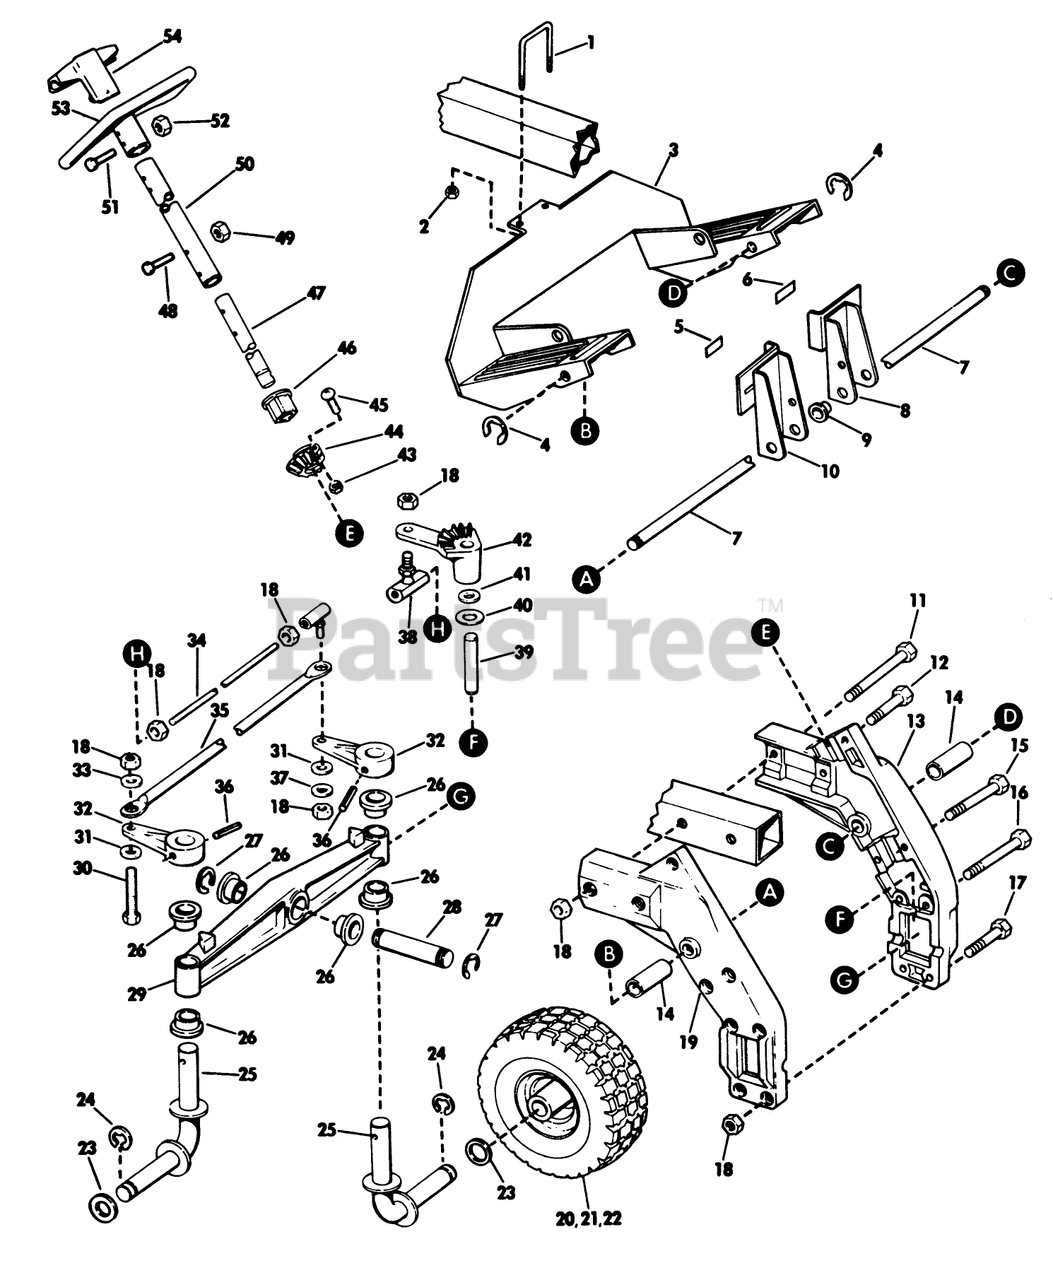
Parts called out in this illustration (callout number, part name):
30	Screw-King Pin
49	STOP NUT
52	Nut-Steering Shaft
